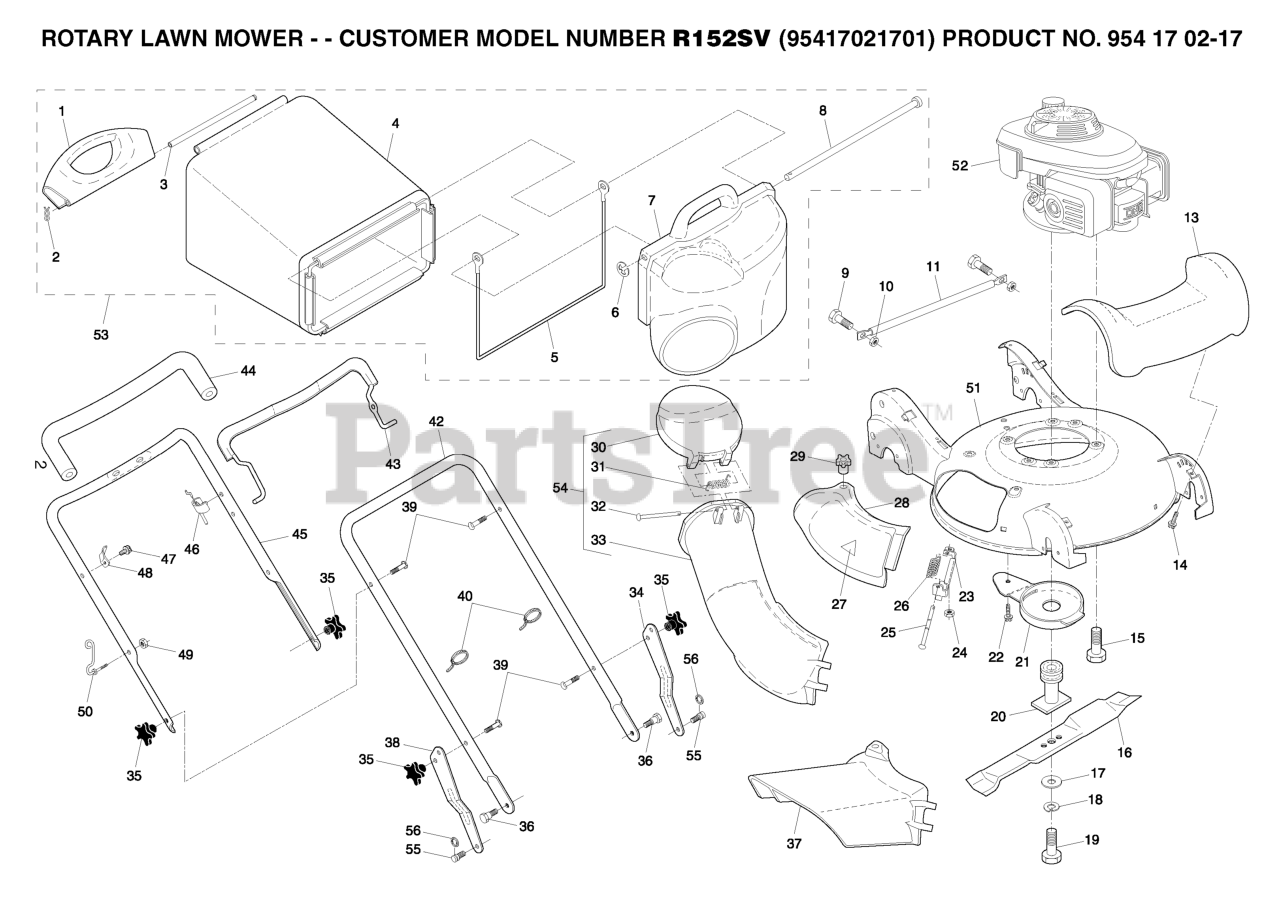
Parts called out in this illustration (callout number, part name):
1	HANDLE.GRASSBAG.REAR.H-GRAY
2	COTTER PIN (3 2)(2 2MC)
3	ROD.REAR.HANDLE.YELLOW
5	FRAME, GRASSBAG
7	DOOR, GRASSBAG
8	ROD, PIVOT
10	LOCKNUT.NYLOC.1/4-20
11	TUBE, REAR SKIRT
13	COVER, FRONT
14	SCREW
15	BOLT 3/8-16X1-1/8
16	Blade, 21"
17	WASHER,HARDEN
18	LOCKWASHER
19	BOLT.HD.HEAD.3/8-24X2.50 (2 2)
20	ADAPTER.BLADE
21	DEBRIS SHEILD
22	SCREW 1/4X20
23	BRACKET.ASM.HINGE
24	LOCK NUT
25	ROD.HINGE.1/4"3.82"
26	SPRING.MULCH.DOOR
27	DECAL.INTERNATIONL.CUTFINGER
28	MULCHER DOOR
29	KNOB.MULCH.DOOR
30	CHUTE.DOOR.21.HV.H-GRAY
32	ROD.HINGE.1/4"3.82"
33	DISCHARGE CHUTE PLASTIC
34	ADJUSTMENT BRACKET, LOWER LH
35	KNOB.HANDLE.STAR.HUSQ.GRAY
36	SHOULDER BOLT
37	GUARD.CLIP.ON.21.HV.GRAY
38	BRACKET.ADJ.LOWER.HDL.RT.GREY
39	BOLT, HANDLE 5/16-18X1.75
40	TIE GUIDE
42	HANDLE.LOWER.GREY
43	BAIL CONTROL
44	GRIP.HANDLE.FOAM.WIDE.(1 SIDE)
45	HANDLE.ASM.UPPER.W/GRIP
46	RB ENGINE ZONE CONTROL CABLE
48	BRACKET
49	NUT
50	GUIDE.ROPE.WALK.MOWER
54	CHUTE.LOWER.ASM.WALK.MOWER
55	STUD, SHOULDER
56	E-RING 7/16 RE
